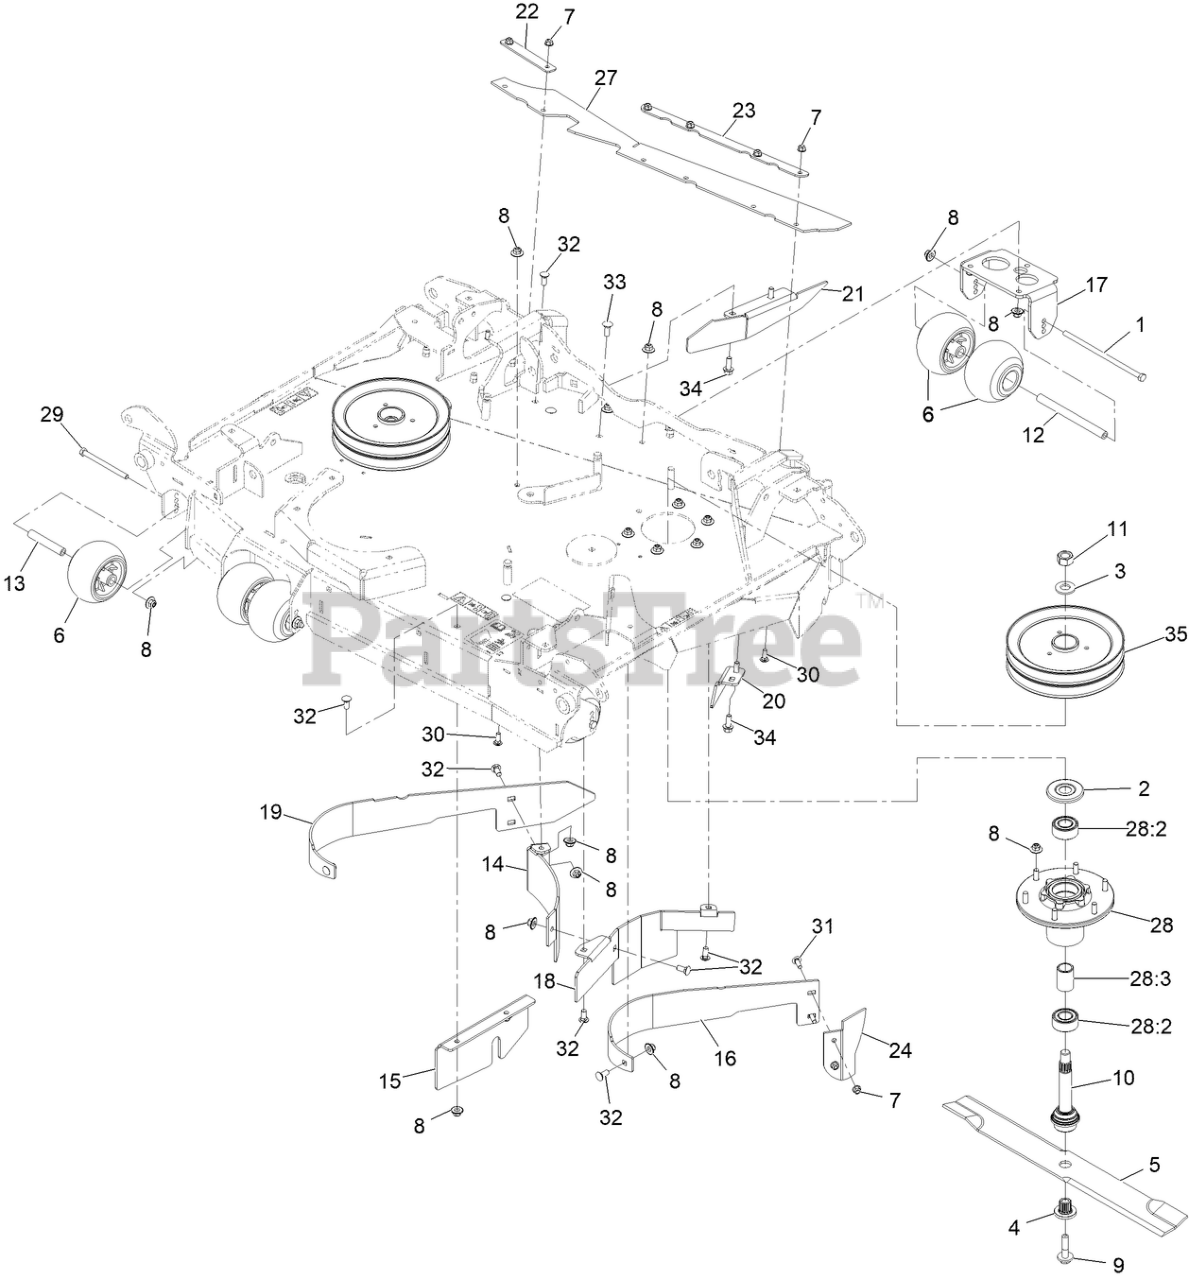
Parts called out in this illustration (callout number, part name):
1	SCREW-HH
2	GUARD-BEARING, TOP
4	BUSHING,SPLINED
6	ROLLER-SCALP, ANTI
7	NUT-HF, NI
8	Nut-Nyloc 3/8-16 Flg
9	SCREW,SEMS 1/2-20 X 2.19
10	ASM-SPINDLE AND SEAL
11	NUT-HEX
12	SPACER-WHEEL
13	SPACER-WHEEL SHORT
14	BAFFLE-CENTER, REAR (RH)
15	PLATE-BLOCK, FRONT
16	BAFFLE-DOGLEG, CENTER (LH
17	BRACKET-ANTISCALP, REAR
18	BAFFLE-CENTER
19	BAFFLE-DOGLEG, CENTER (RH
20	BAFFLE-BREAKER
21	PLATE-FIN, DISCHARGE
22	SUPPORT-FLAP, LH
23	SUPPORT-FLAP, LH
24	GUARD-DISCHARGE
27	FLAP-DISCHARGE
28	ASM-CUTTER HSG
28:2	BEARING-3205 TRASHGUARD
28:3	SPACER-BEARING
29	SCREW-HH
30	SCREW-CARR
31	SCREW-CARR
32	BOLT-CARR
33	BOLT-CARR
34	SCREW-HHF
35	SHEAVE-DOUBLE 96RD
